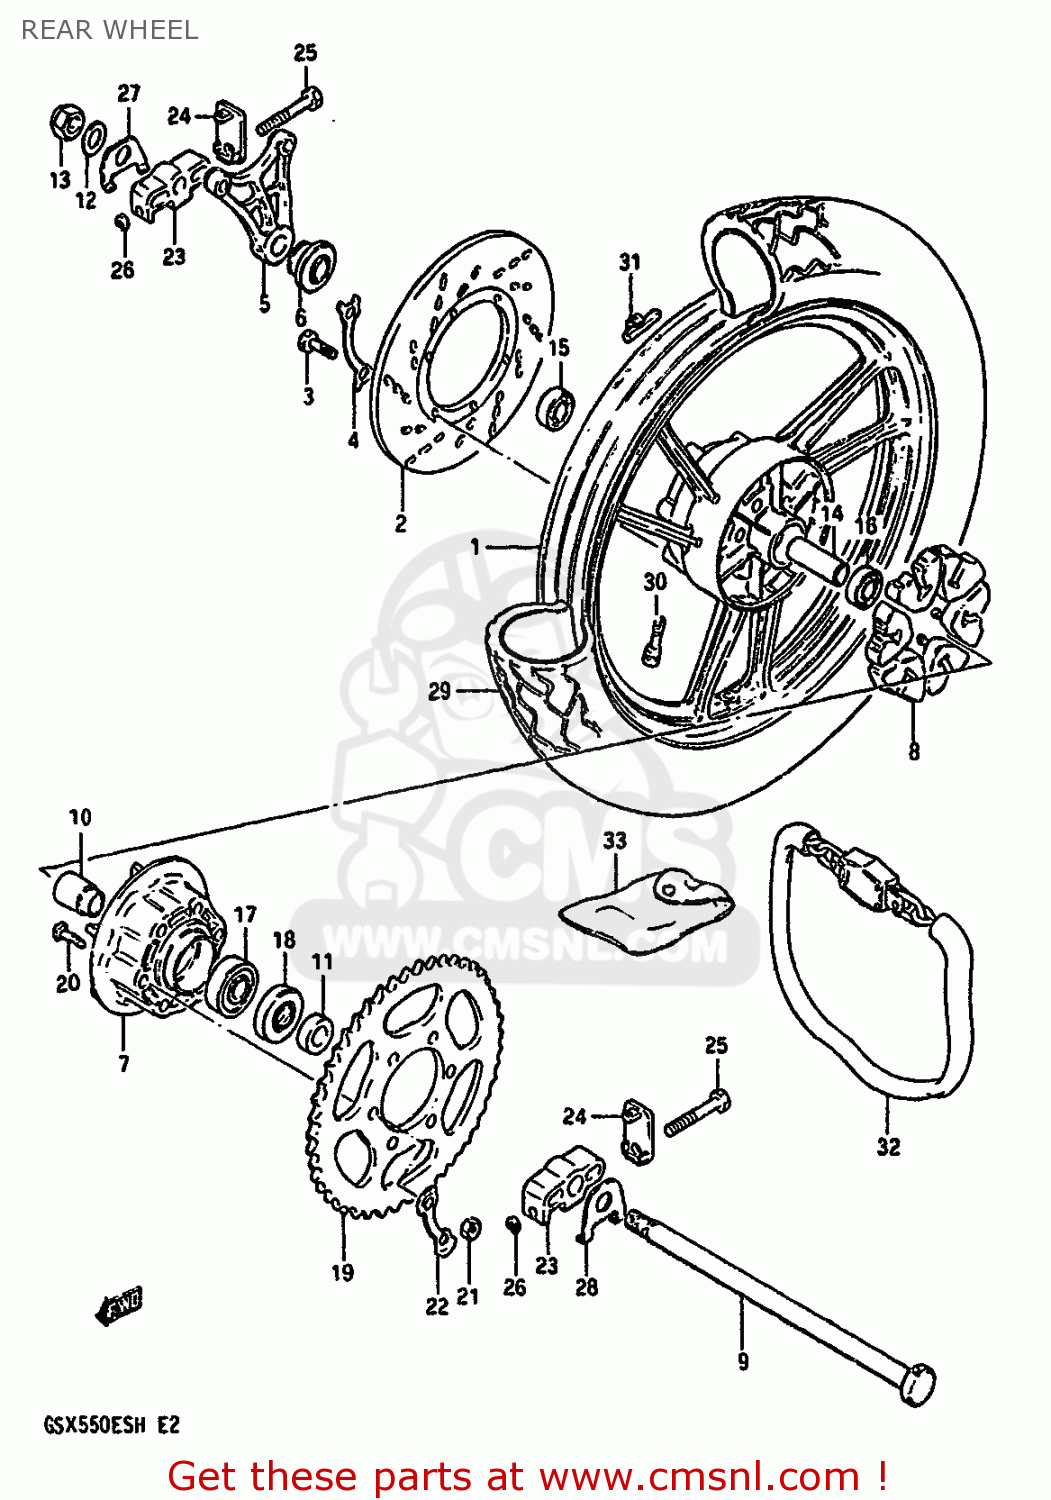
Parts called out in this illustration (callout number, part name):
1	WHEEL,REAR
2	DISC,REAR BRAKE
3	BOLT(8X25)
4	WASHER
5	BRACKET,RR,CALIPER
6	SPACER,REAR AXLE,RIGHT
7	DRUM,REAR SPROCKET MOUNT
8	ABSORBER,RR HUB SHOCK
9	AXLE,REAR
10	SPACER,REAR HUB BEARING
11	SPACER (17X30.5X13.5)
12	WASHER
13	NUT
14	SPACER(17.5X25X81)
15	BEARING
16	BEARING
17	BEARING
18	SEAL,OIL(30.5X52X8)
19	SPROCKET, REAR (NT:46)
20	BOLT(10X35.5)
21	NUT
22	WASHER
23	BODY,CHAIN ADJUSTER
24	PLATE,CHAIN ADJUSTER
25	BOLT,CHAIN ADJUSTER
26	E RING
27	WASHER,CHAIN ADJUSTER RH
28	WASHER,CHAIN ADJUSTER
29	TIRE
30	VALVE,TIRE
31	BALANCER,WHEEL
32	CHAIN LOCK ASSY
33	BAG,CHAIN LOCK
